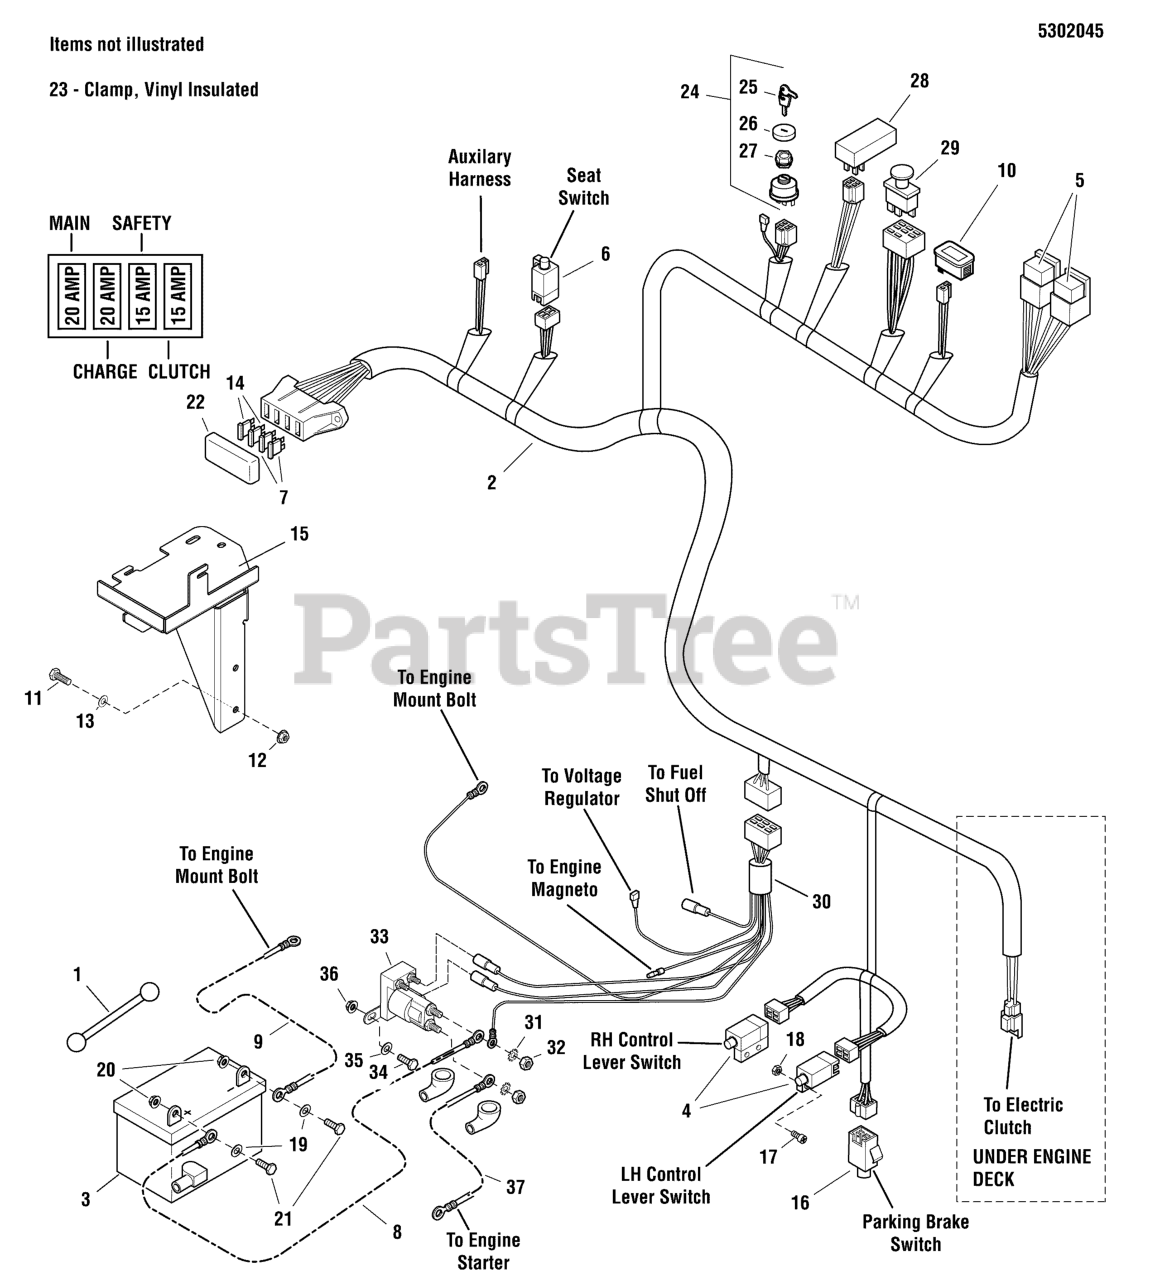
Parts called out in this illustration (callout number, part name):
1	STRAP-BLACK RUBB
2	WIRE HARNESS, MAIN, S75X
3	BATTERY, WET (BCIU1, 340 CCA)
4	SWITCH, PLUNGER, N.O.
5	RELAY, 12V, 40A
6	SWITCH, PLUNGER, NO/NO BOLT-ON
7	FUSE, ATO-15 (15 AMP)
8	BATTERY, CABLE, POSITIVE 22"
9	BATTERY CABLE, NEG, 22, 1/4-5/16
10	HOUR METER
11	BOLT, 3/8-16 X 1" GD5 CZ
12	NUT, 3/8-16 HEX NYLOCK FLANGE
13	WASHER, 3/8 SAE
14	FUSE, ATO, 20 AMP
15	WELD, BATTERY MOUNT - RED
16	SWITCH, DP NO/NC SNAP-IN
17	SCREW- #10-24 X 1/2 ROUND PHILLIPS
18	NUT, #10-24 HEX NYLON LOCK
19	WASHER, 1/4 SAE
20	NUT, 1/4-20 HEX NYLOCK FLANGE
21	BOLT, 1/4-20 X 3/4 GD5 YZ
24	SWITCH, IGNITION, 6 POST
25	KEY, IGNITION MOLDED SET
26	COVER, PLASTIC, SNAP ON
27	PLASTIC NUT
28	MODULE, TIME DELAY
29	SWITCH, BLADE ENGAGEMENT
30	WIRE HARNESS, JUMPER, S75X22HP
31	WASHER, 5/16 LIGHT LOCK
32	NUT, 5/16-24 HEX
33	SOLENOID-4 POLE, 12 VOLT DC
34	BOLT, 1/4-20 X 3/4 GD5 YZ
35	WASHER, 1/4 SAE
36	NUT, 1/4-20 HEX NYLOCK FLANGE
37	BATTERY, CABLE, POSITIVE 15"
